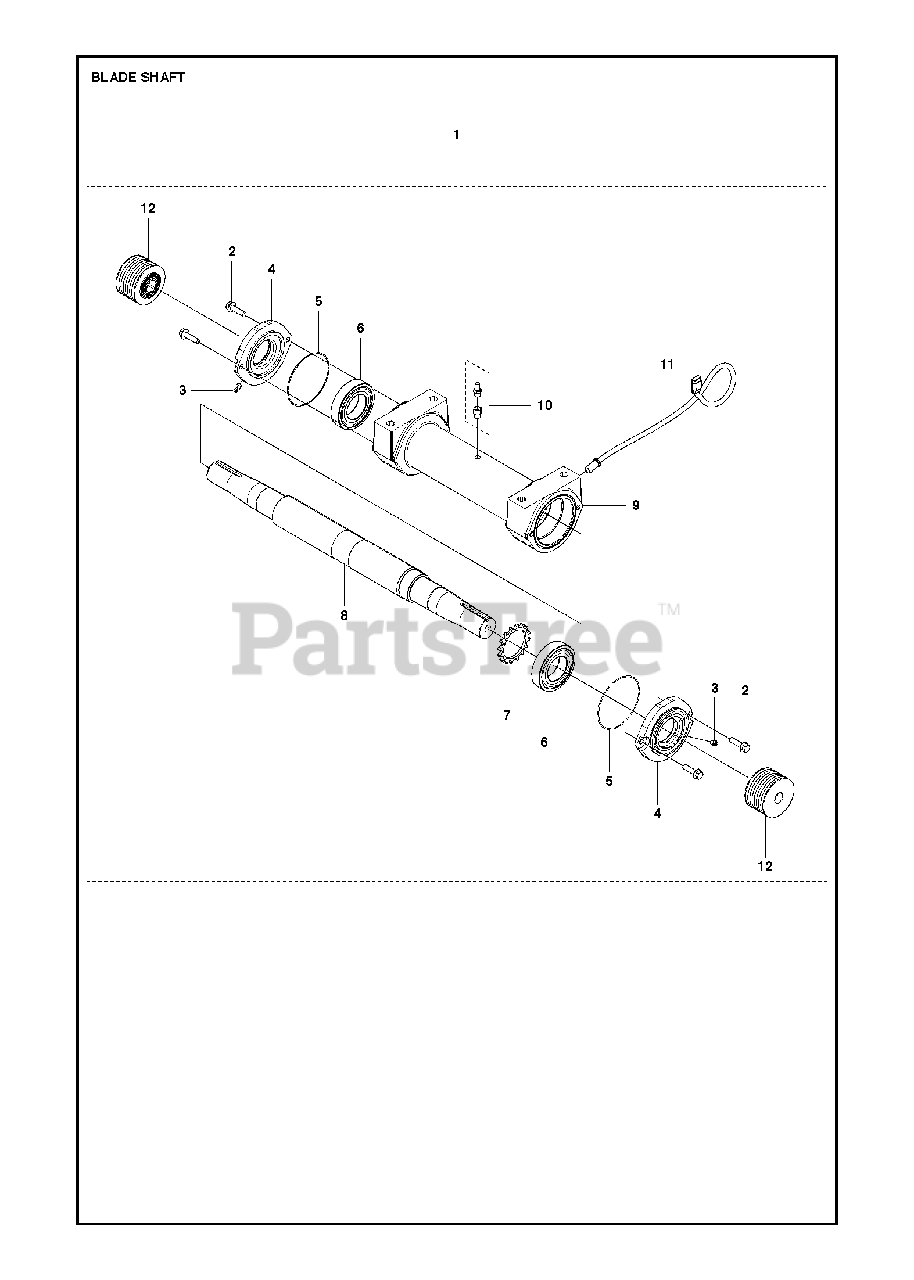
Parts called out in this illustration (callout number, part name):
1	SHAFT ASSY14"-20" 1-speed"
1	SHAFT ASSY26" 1&3-speed
1	SHAFT ASSY30" 1-speed
1	SHAFT ASSY36" 1-speed
1	SHAFT ASSY30" 3-speed
1	SHAFT ASSY36" 3-speed
12	PULLEYFor 14"-20" 1 speed and 26" 1&3-speed
12	PULLEYFor 30" 3-speed
12	PULLEYFor 30" 1-speed
12	PULLEYFor 26" 1&3-speed
12	PULLEYFor 36" 1-speed
